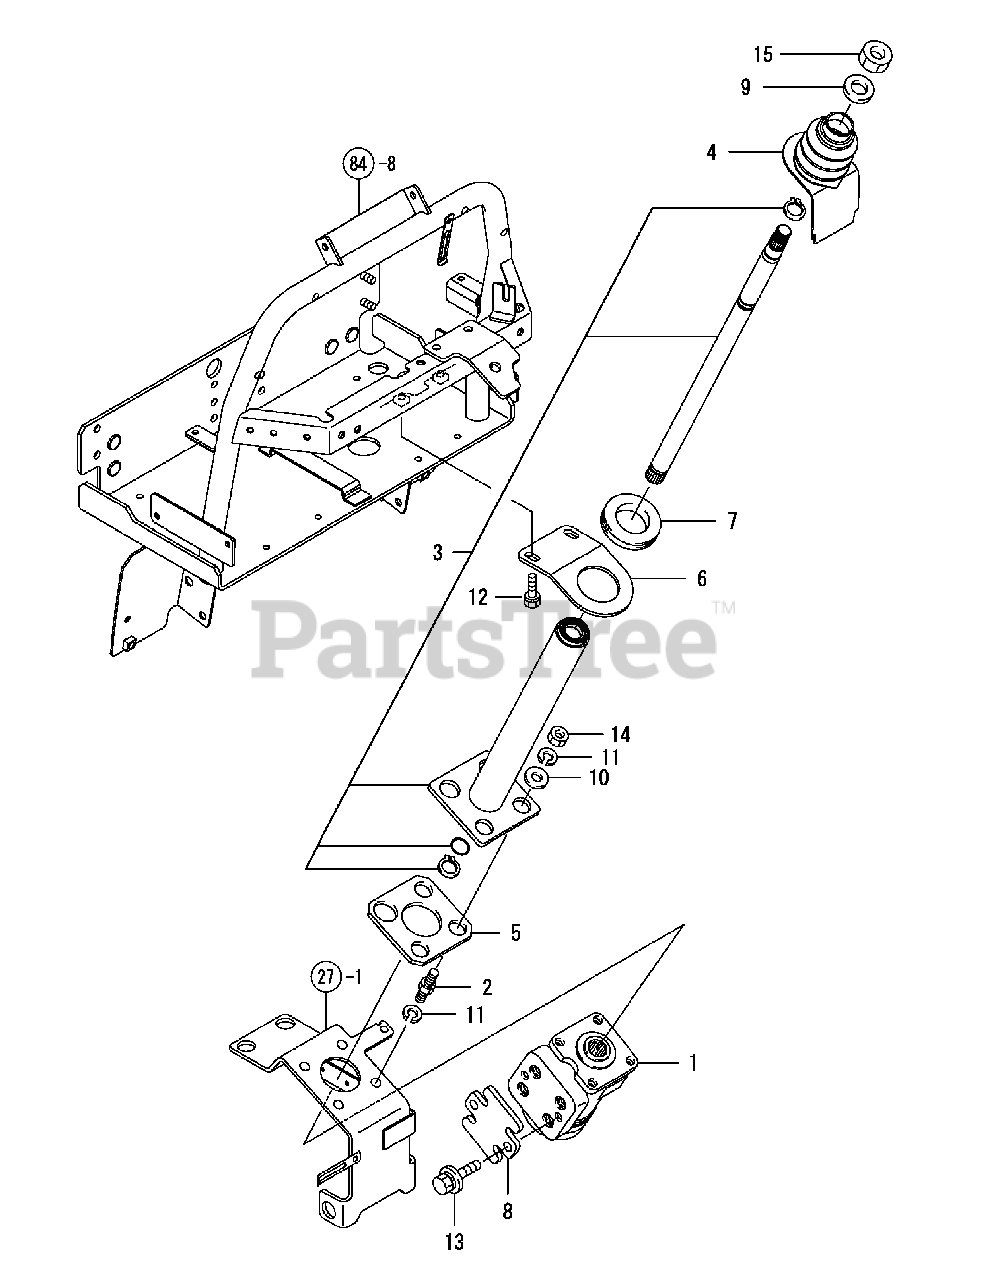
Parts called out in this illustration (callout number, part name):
1	Valve Assy, Steering
4	Boot, Steerring
5	Plate, St Colum
9	Washer 16,Polished
11	Spring Washer 10
12	Bolt W/Washer M8X20
15	Lock Nut M16 Plated
